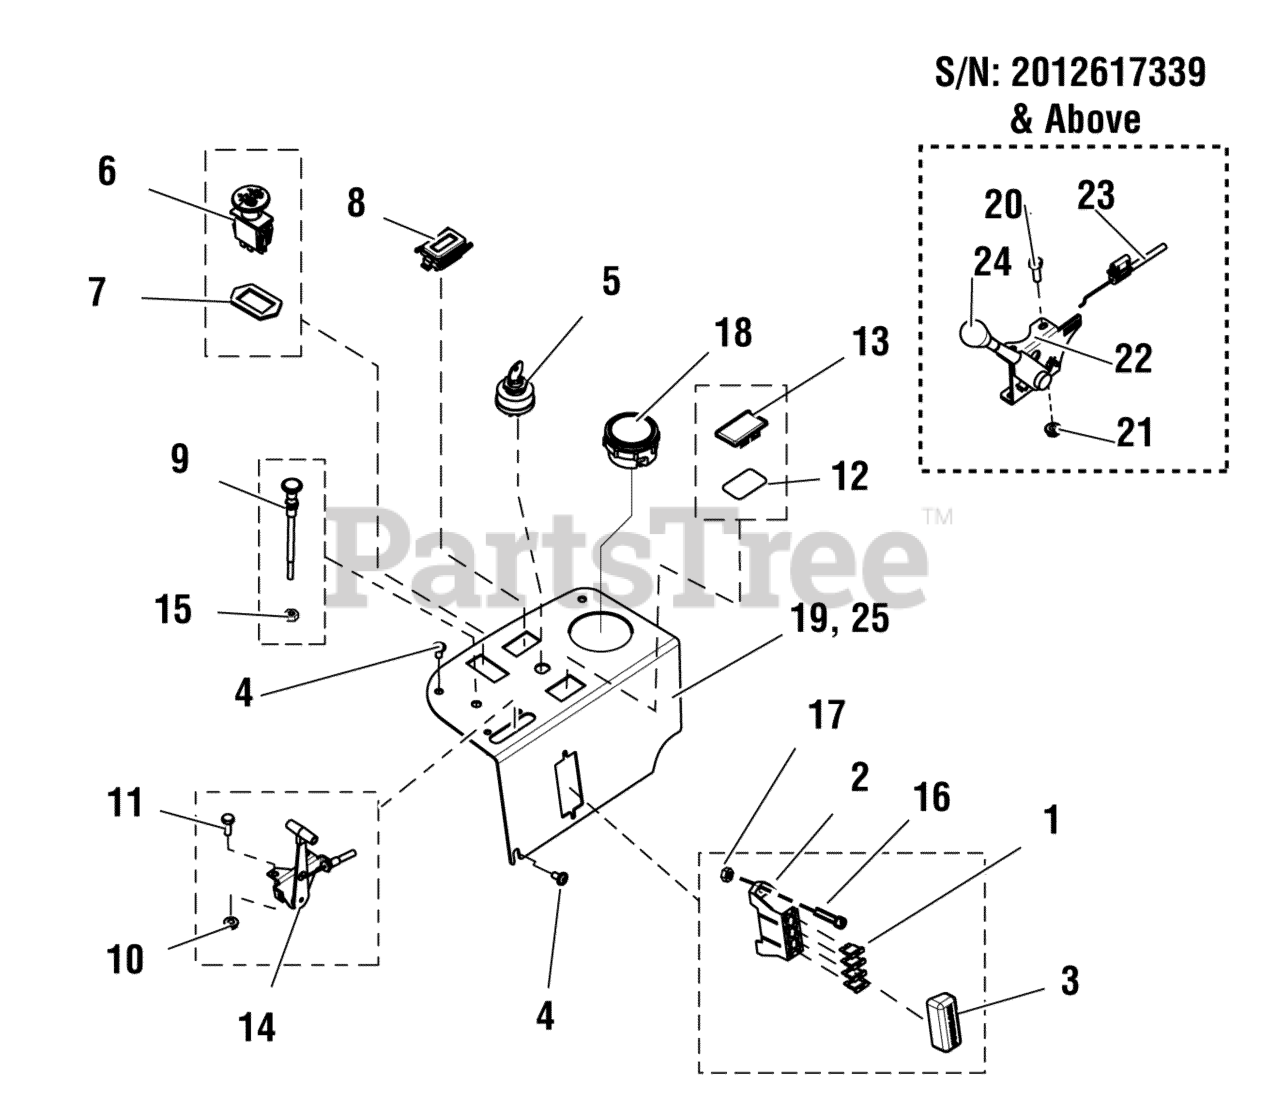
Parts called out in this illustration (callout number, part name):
1	FUSE, ATO 20 AMP
2	FUSE, BLOCK
3	COVER, VINYL FUSEBLOCK
4	SCREW, 1/4-20 X 1/2" ALLEN BH
5	SWITCH, IGNITION, 6 POST
6	SWITCH, BLADE ENGAGEMENT
7	RING, SWITCH RETAINER
8	HOUR METER
9	CABLE, CHOKE CONTROL, 47"
10	NUT, 1/4-20 HEX SERR. FLANGE
11	BOLT, 1/4-20 X 3/4" GD5 YZ
12	O-RING, 7/8" ID X 1/16"
13	PLUG, .820X1.44 HOLE, BLACK PLASTIC
14	CABLE, THROTTLE CONTROL, 45"
15	NUT, 3/8 - 24 HEX
16	SCREW, #10-24 X 2" ROUND PHILLIPS
17	NUT, #10-24 HEX NYLON LOCK
18	GUAGE, WATER TEMPERATURE
19	PANEL, CONTROL, IS2000Z 26/61 - BLK
20	SCREW, #10-24 X 3/4"
21	NUT, #10-24 HEN NYLON LOCK
22	LEVER, THROTTLE CONTROL, HEAVY-DUTY
23	CABLE, THROTTLE, 42"
24	THROTTLE CONTROL HANDLE/KNOB
25	PANEL, CONTROL, IS2000Z LC
